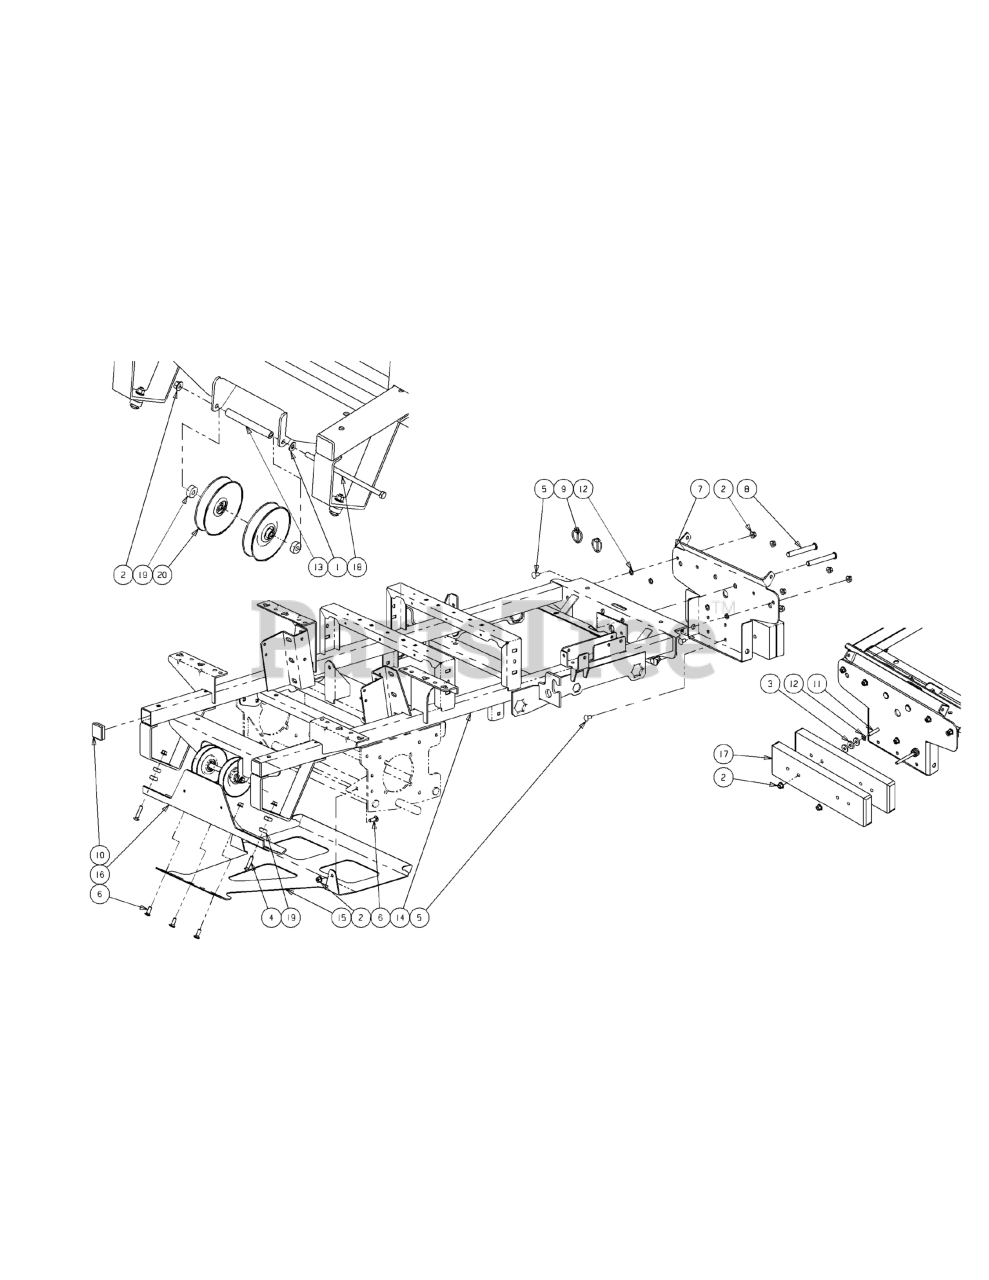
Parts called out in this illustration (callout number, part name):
1	Flat Washer, 3/8
2	Hex Nut, 3/8-16 Flange Lock
3	Idler Washer
4	Hex Carriage Screw, 3/8-16, 1.75
5	CARRIAGE BOLT 3/8-16 x .75
6	Carriage Bolt, 3/8-16 x 1
7	Bracket Assembly, Frame, Front
8	Clevis Pin, .625 Dia x 4.375 Long
9	Linch Pin, 3/16 Dia.
10	Plug, Square Tube
11	Carriage Bolt, 3/8-16 x 4.0
12	Push Retainer, 3/8"-Thread Stud
13	Spacer, .385 ID x .625 OD x 4.89
14	Frame Assembly
15	Skid Plate
16	Guard Bracket
18	Hex Head Cap Screw, 3/8-16 x 8.50
19	Spacer .406 ID x 1.0 OD
20	Idler Pulley, 5.06 Dia.
